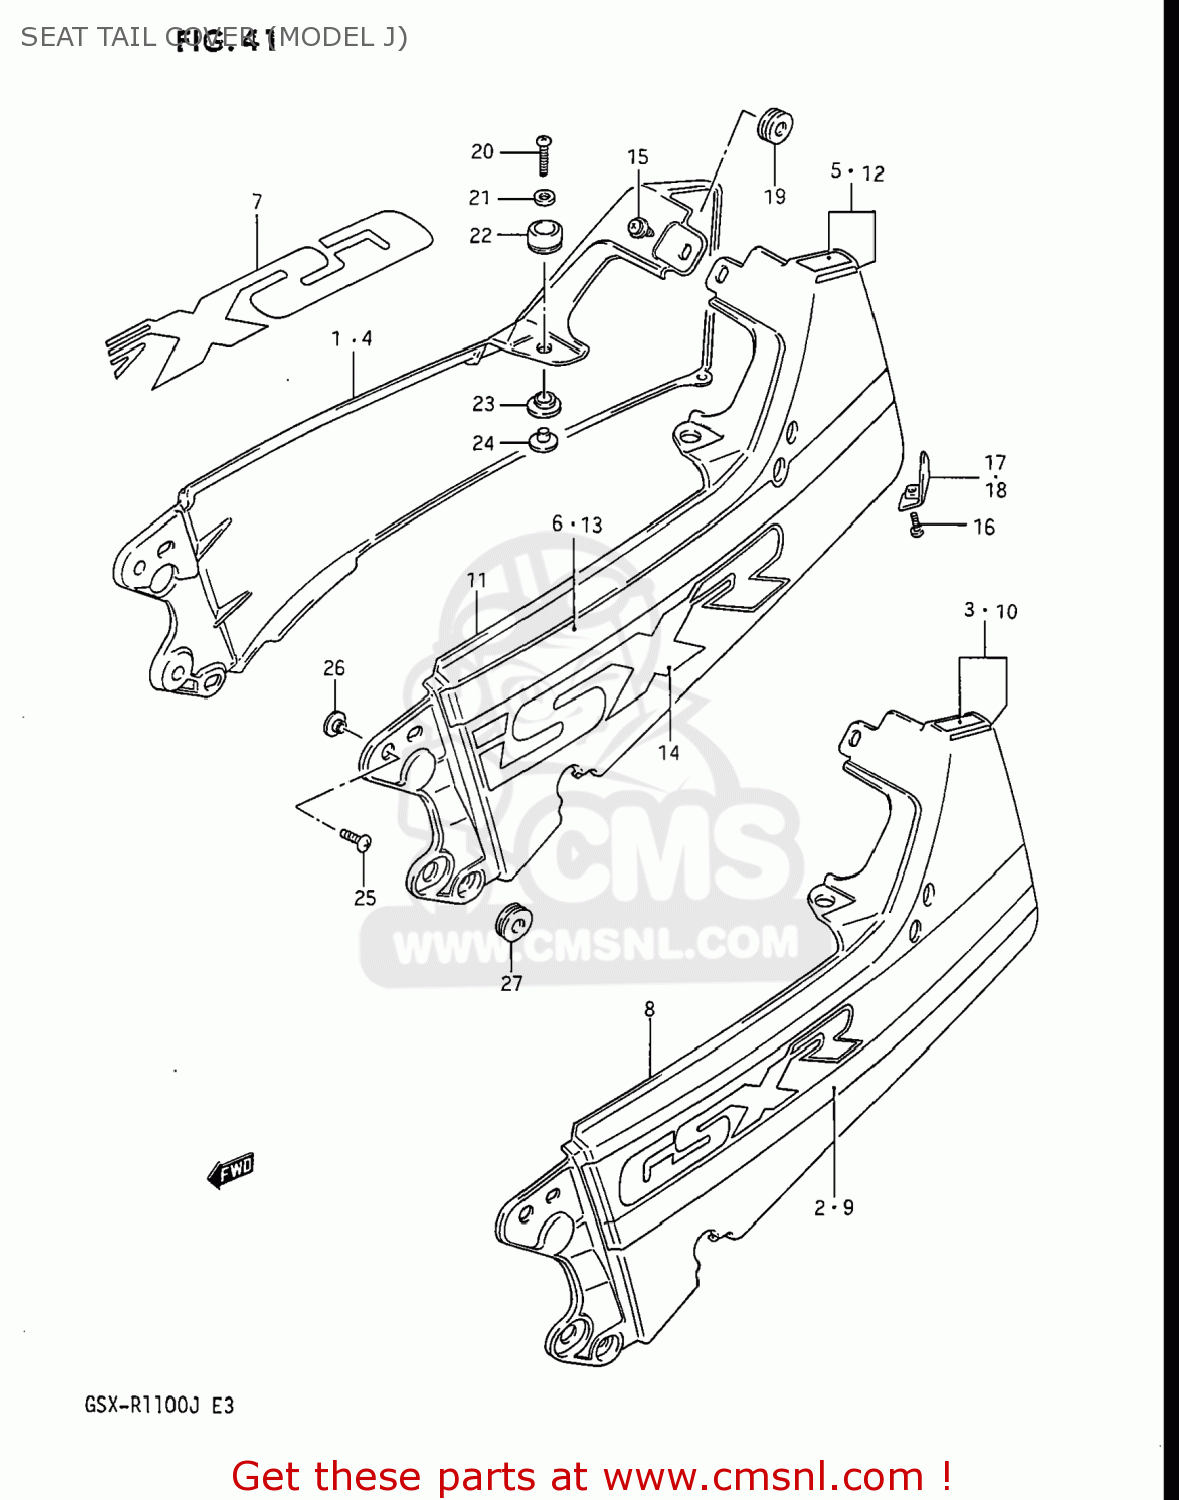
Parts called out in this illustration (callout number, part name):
1	COVER COMP,SEAT TAIL
2	TAPE,SEAT TAIL COVER,RIGHT
3	TAPE,SEAT TAIL COVER,RIGHT
4	COVER COMP,SEAT TAIL
5	TAPE,SEAT TAIL COVER,RIGHT
6	TAPE,SEAT TAIL COVER,RIGHT
7	EMBLEM,RIGHT
8	COVER,SEAT TAIL
9	TAPE,SEAT TAIL COVER,LEFT
10	TAPE,SEAT TAIL COVER,LEFT
11	COVER,SEAT TAIL
12	TAPE,SEAT TAIL COVER,LEFT
13	TAPE,SEAT TAIL COVER,LEFT
14	EMBLEM,LEFT
15	CLIP
16	SCREW
17	PLATE,SEAT TAIL COVER,RH
18	PLATE,SEAT TAIL COVER,L
19	CUSHION
20	SCREW
21	WASHER
22	CUSHION,TAIL COVER UPR
23	CUSHION,TAIL COVER LWR
24	SPACER,SEAT TAIL COVER
25	SCREW
26	WASHER
27	CUSHION
